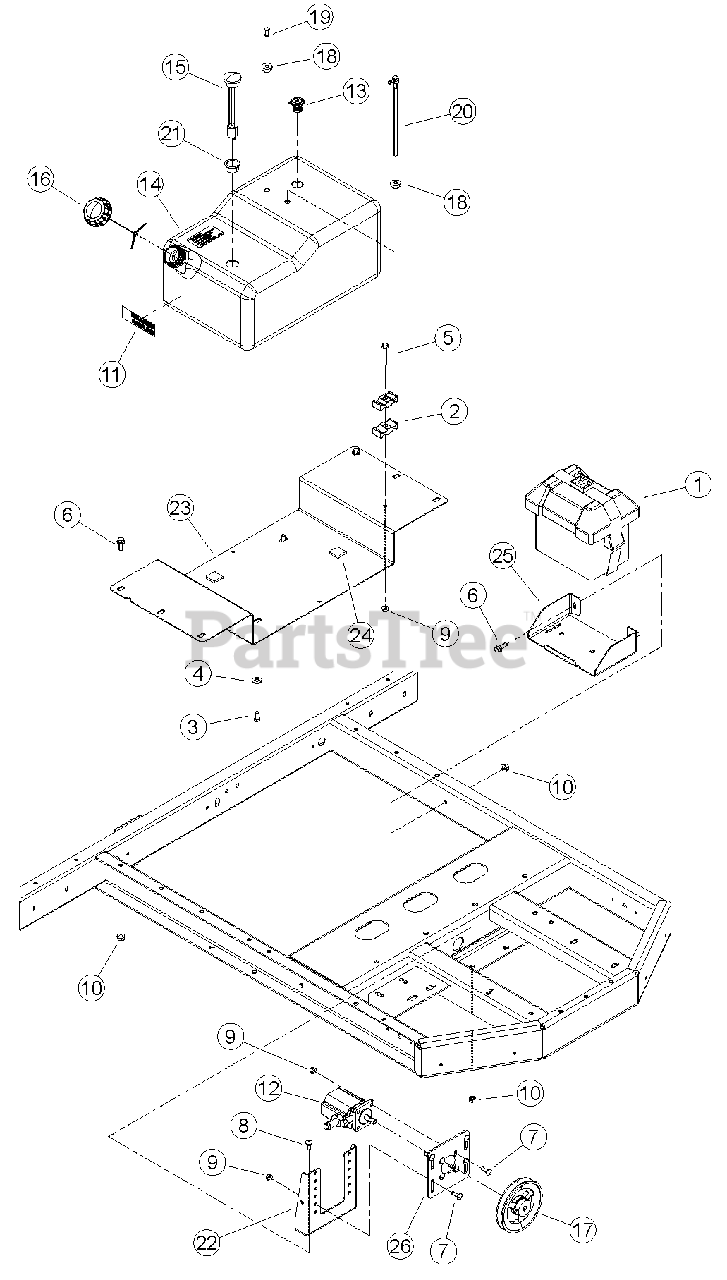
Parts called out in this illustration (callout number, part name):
1	BOX, SMALL BATTERY
2	CLAMP, PLASTIC HOSE
3	BOLT, 3/8 X 3/4 GR5 HEX CAPSCREW ZP
4	WASHER, 3/8" FLAT ZP
5	BOLT, 5/16 X 2-1/4 FLANGE NC
6	BOLT, 3/8 X 1 FLANGE NC
7	BOLT, 5/16 X 1" GR5 CRG ZP
8	BOLT, 5/16 X 7/8" GR5 CRG NC ZP
9	NUT, 5/16-18 NYLOCK FLANGE
10	NUT, 3/8-16 NYLOCK FLANGE
11	DECAL, UNLEADED GASOLINE
12	PUMP, 2 STAGE CW HI/LO 0.605 DISP.
13	VALVE, ROLL OVER
14	TANK, ROTOMOLDED FUEL
15	GAUGE, FUEL LEVEL KELCH 100
16	CAP, NON-VENTED EPA/CARB APPROVED
17	PULLEY, 5.6 - 1/2" BORE FHP B
18	GROMMET, TANK FITTING
19	PLUG, TANK VENT
20	FITTING, TANK FUEL PICK-UP TUBE
21	GROMMET, KELCH 100 GAUGE
22	BRACKET, MOUNT HYDRAULIC PUMP
23	BASE, 9.25 GAL NYLON TANK
24	PAD, FOAM FUEL TANK DAMPER
25	BRACKET, BATTERY HOLDER
26	PLATE, HYDRAULIC PUMP
